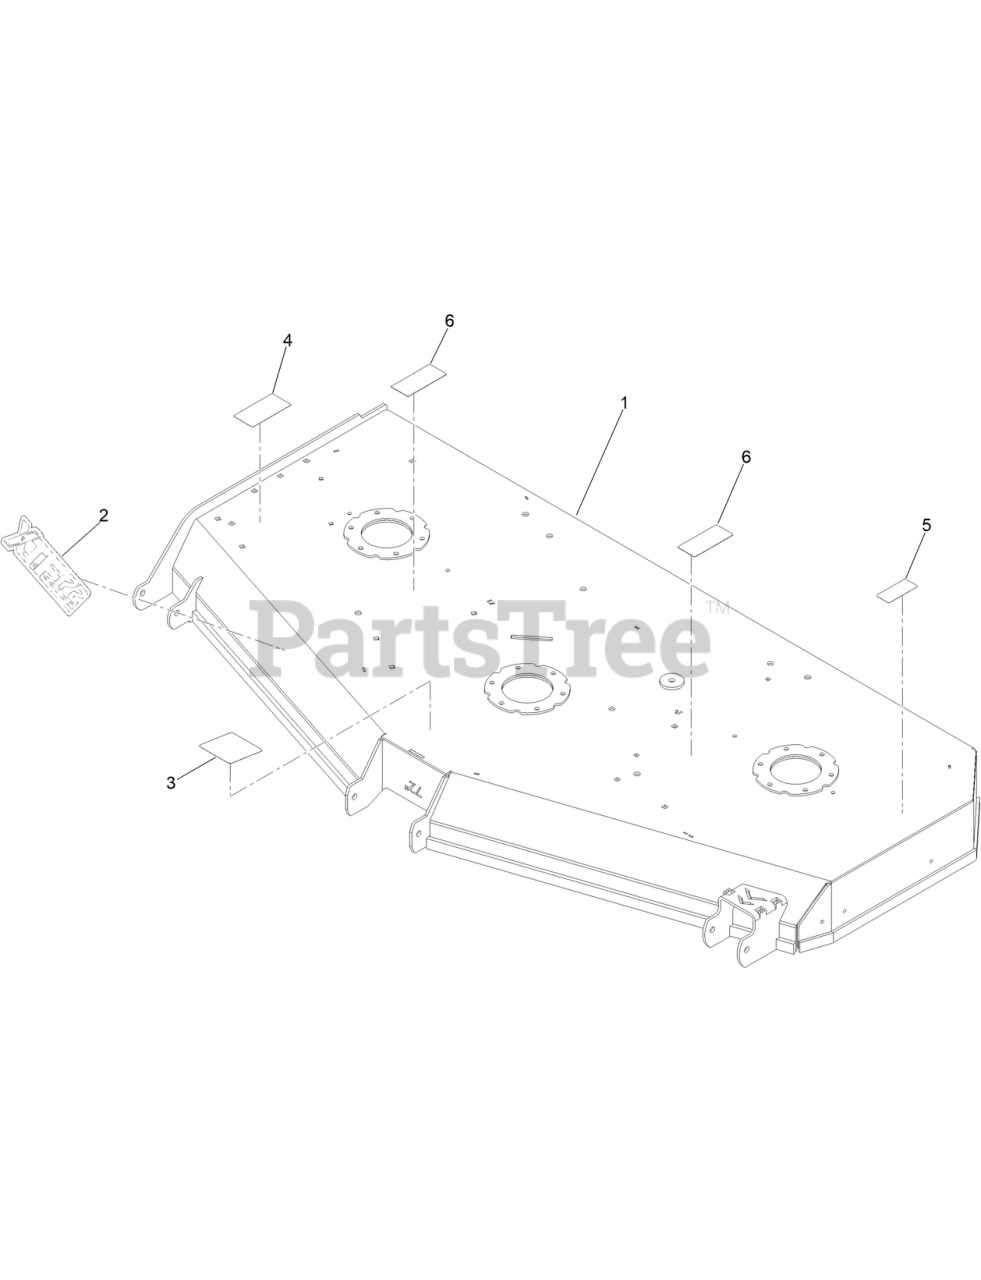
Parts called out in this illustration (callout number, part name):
1	DECK ASM-72 PAINTED
2	2020 XTF-72 DECAL
3	DECAL-DECK BELT ROUTING
4	DECAL-DANGER, DECK
5	DECAL-SAFETY BLADE TORQUE
6	DECAL-ROTATING FAN HAZARD
